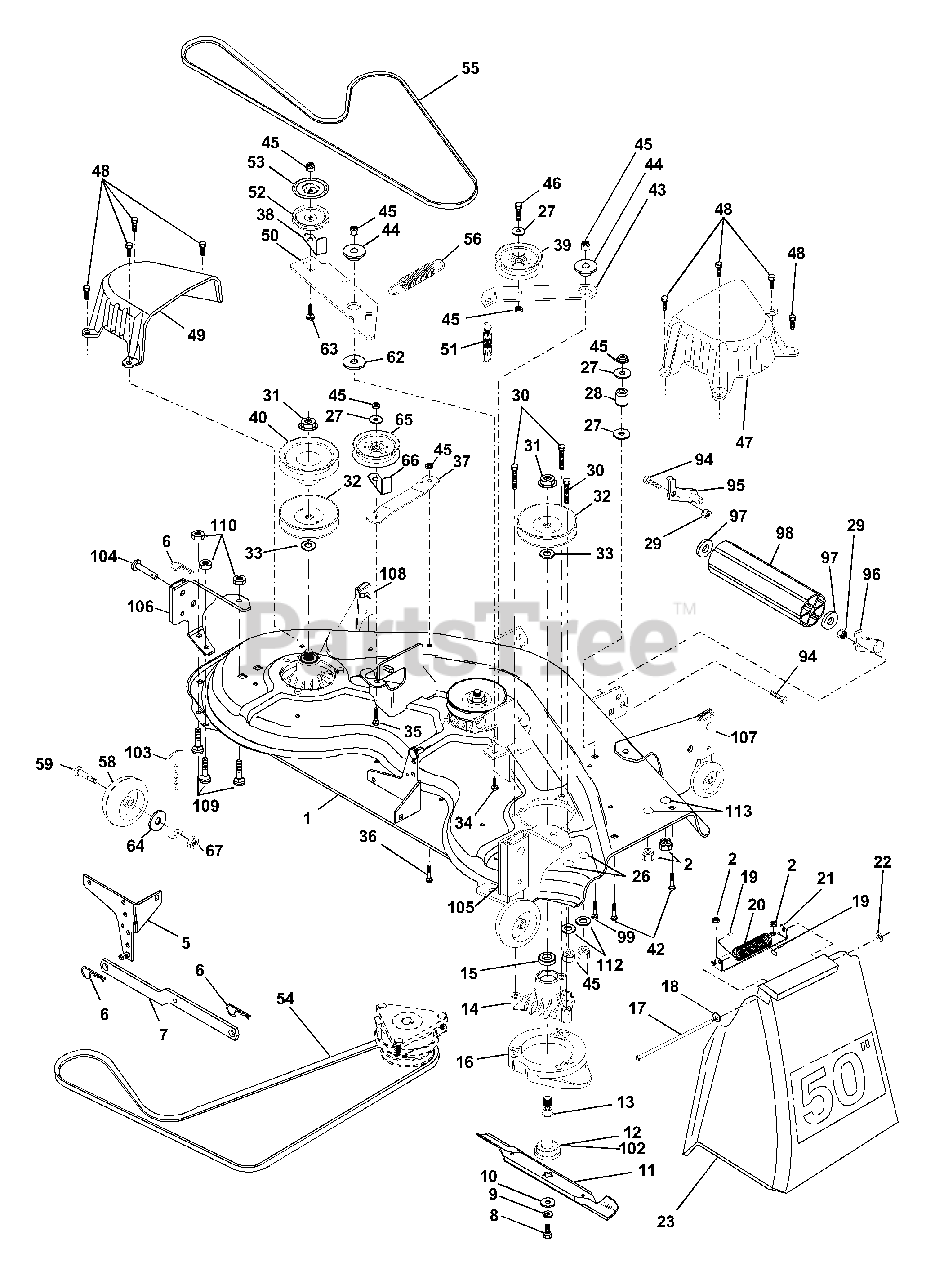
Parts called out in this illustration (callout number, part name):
1	Deck Asm., Mower 50"
2	Nut, Crownlock 5/16-18
5	Bracket Asm., Sway Bar
6	Retainer, Spring
7	Arm Suspension, Rear
8	Bolt 3/8-24 x 1.25 Gr. 8 Patched
9	Washer, Lock Hvy 3/8 Unplated
10	Washer, Hard Blade Mower Vented
11	Blade (3 Required)
12	Bearing, Ball #6204 (Mandrel)
13	Shaft Asm., W/Lower Brg
14	Housing, Mandrel 50" Vent
15	Bearing, Ball Mandrel
16	Stripper, Mower Vented
17	Rod, Hinge
18	Washer 11/32 x 5/8 x 16 Ga.
19	Cap Sleeve
20	Spring, Torison Delector
21	Bracket, Deflector
22	Nut, Push
23	Shield, Deflector Mower
25	Washer 11/32 x 3/4 x 16 Ga.
26	Bolt Rd Hd Sht Sqnk
27	Washer 13/32 x 13/16 x 16 Ga.
28	Spacer, Spring Stop Idler
29	Nut, Lock Hex W/Wsh 3/8-16 Unc
30	Screw Thd Rolling Washer Head
31	Nut, Flg Top Lock Cntr 9/16
32	Pulley, Mandrel
33	Washer, Spacer Mower Vented
34	Bolt, Carriage 3/8-16 x 1-1/4
35	Bolt, Carriage 3/8-16 x 2
36	Bolt, Carriage 3/8-16 x 1 Gr. 5
37	Stiffener, Arm Idler
38	Keeper, Belt Idler
39	Pulley, Idler Flat
40	Pulley, Driven
42	Bolt, Carriage 5/16-18 Unc x 3/4
43	Arm, Idler Secondary
44	Spacer, Retainer
45	Nut, Crownlock 3/8-16 Unc
46	Bolt, Fin Hex 3/8-16 Unc x 1-3/4
47	Cover, Mandrel RH
48	Screw, Thd Roll 1/4-20 x 5/8
49	Cover, Mandrel LH
50	Arm, Idler Primary
51	Spring, Secondary
52	Pulley, Idler V Groove
53	Shield, Idler
54	V-Belt, Mower Primary
55	V-Belt, Mower Secondary
56	Spring, Primary
58	Wheel, Gauge
59	Bolt, Shoulder
62	Washer Hardened
63	Bolt Carriage 3/8-16 x 1-1/2
64	Washer 3/8 x 7/8 x 14 Ga.
65	Pulley Idler Flat Mower
66	Keeper, Belt Idler 50" Vent
67	Nut, Center Lock 3/8-16
94	Bolt H 3/8-16 x 1
95	Bracket, Asm. Noseroller LH
96	Bracket, Asm. Noseroller RH
97	Washer 17/32 x 7/8 x 16 Ga.
98	Roller, Nose
99	Bolt, Carriage 3/8-16 x 1-3/4 Gr. 5
102	Washer Felt
103	Bar Adj. Gauge Wh.
104	Pin Head Rivot
105	Bracket Ga Wh Asm RH 50
106	Bracket Ga Wh Asm LH 50
107	Bracket Ga Wh Assy F RH 50
108	Bracket Ga Wh Assy F LH 50
109	Bolt Carraige 5/16- 18 x 5/8
110	Nut Crownlock 5/16-18
112	Washer 17/32 x 3/4 x 16 Ga.
113	Bolt Carriage 5/16-Unc 1/2
